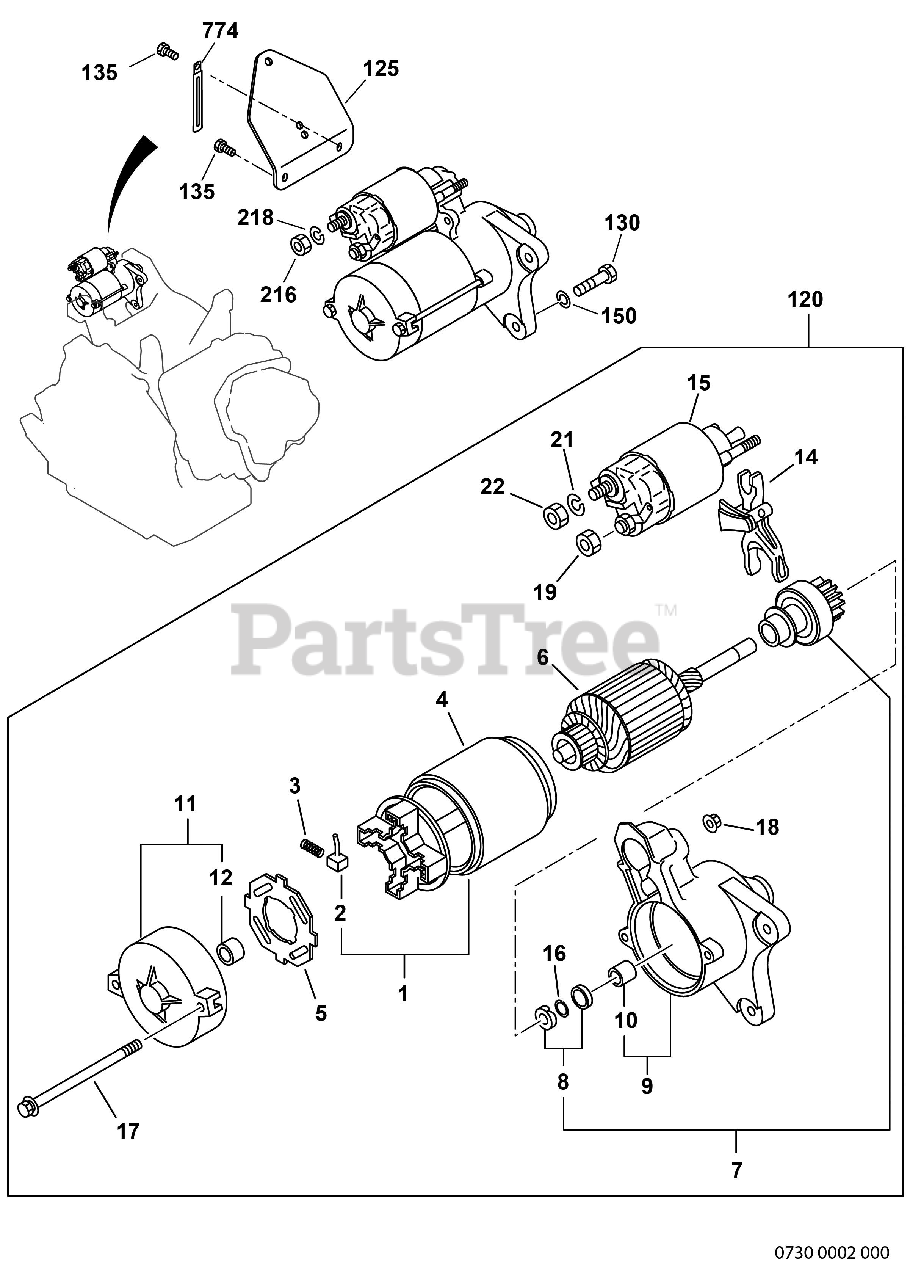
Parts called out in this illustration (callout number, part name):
7	OVER RUNNING CLUT CP
8	PINION STOPPER
15	MAGNET SWITCH CP
120	STARTING MOTOR AY
125	BRACKET (SEL) CP
